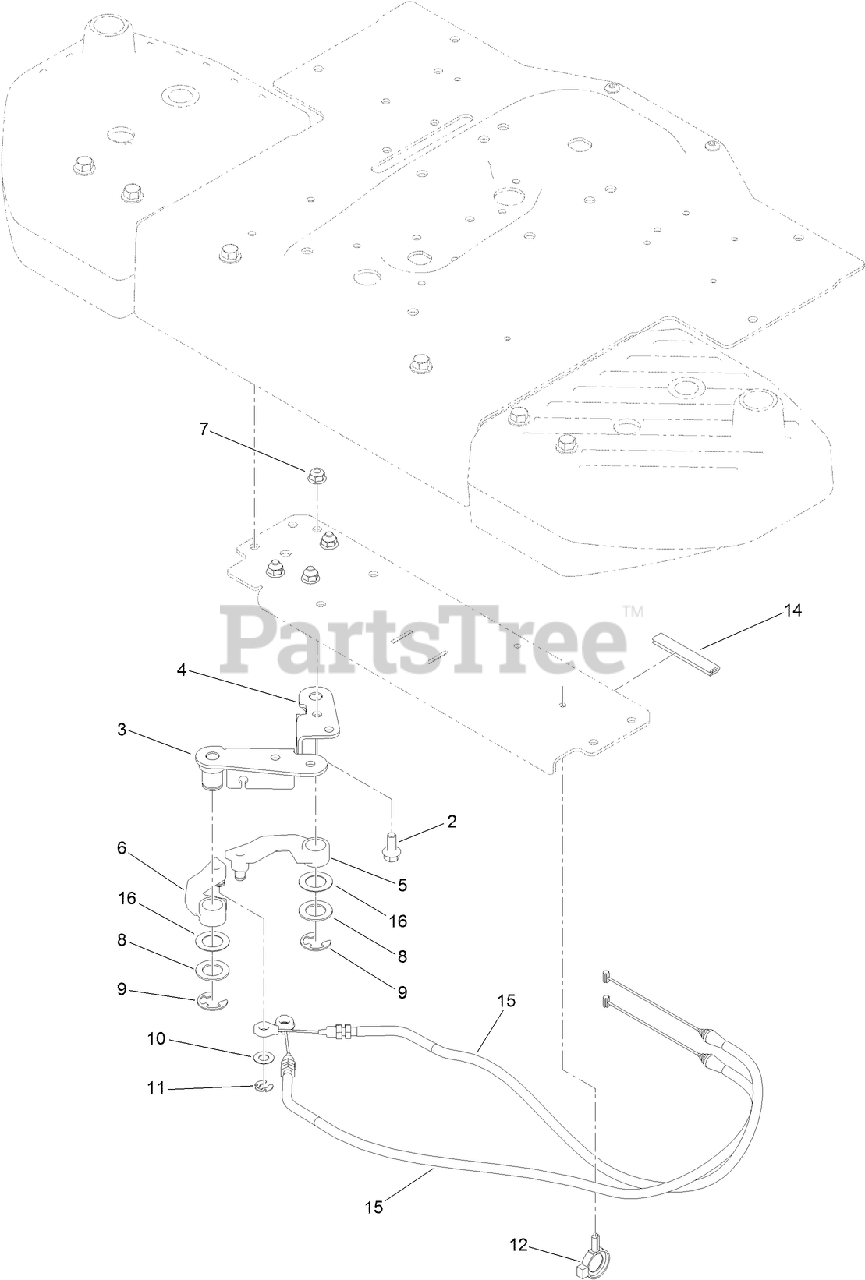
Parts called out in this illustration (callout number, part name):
2	SCREW-HHF
3	CABLE BRACKET ASM
4	CABLE BRACKET ASM
5	ARM-CABLE, RH
6	ARM-CABLE, LH
7	NUT-HF, NI
8	WASHER-THRUST
9	E-RING
10	WASHER-THRUST
11	RING-RETAINING
12	CLAMP-HOSE
14	STRIP-SEAL
15	CABLE-STEERING
16	WASHER-THRUST
